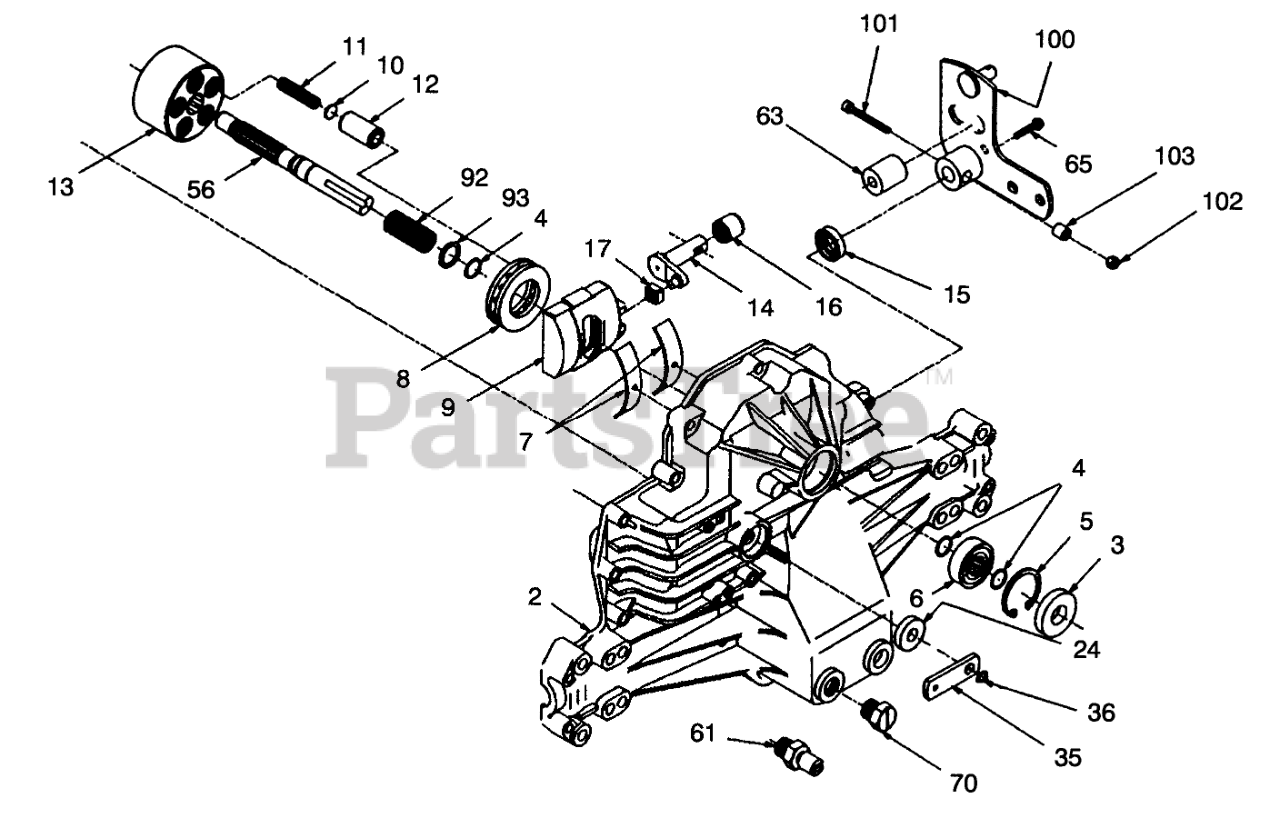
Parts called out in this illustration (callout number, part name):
2	Housing-Upper
3	SEAL-LIP
4	Ring-Wire Retaining
6	Bearing-Shaft Ball
7	Bearing-Cradle
9	Swashplate-Variable
10	Washer-Piston Thrust
11	Spring-Piston
13	Block Cylinder (Motor)
14	Arm-Trunnion
15	SEAL-LIP
16	Bearing-Trunnion Journal
17	Guide-Slot
24	SEAL-LIP
35	ARM - BYPASS
36	RING-RETAINING
61	BREATHER ASSEMBLY
65	Bolt
70	Plug-Plastic
92	Spring-Block
93	Washer-Block Thrust
100	SPEED CNTRL LEVER WA
101	SCREW-HSH
102	NUT-LOCK, NI
103	LOCK SPACER
